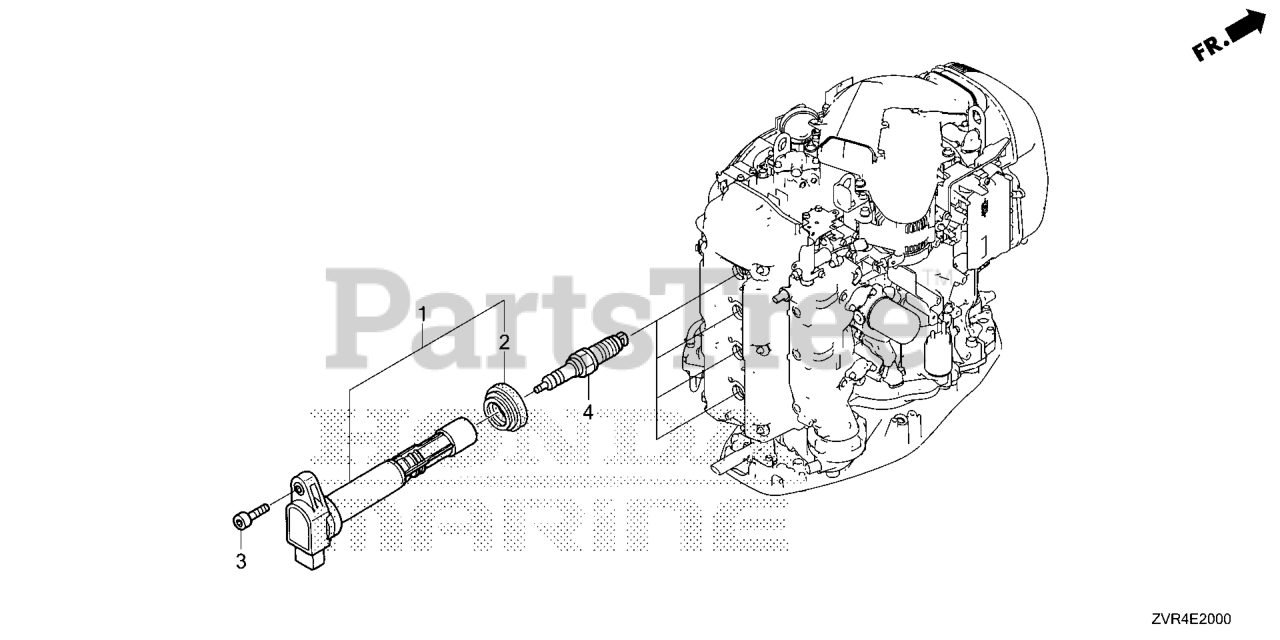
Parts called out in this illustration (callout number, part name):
1	COIL, PLUG HOLE
2	SEAL, PLUG HOLE
3	BOLT, SOCKET (6X25)
4	SPARK PLUG (KJ20DR-M11) (DENSO)
4	SPARK PLUG (SKJ20DR-M11) (DENSO)
4	SPARK PLUG (ZFR6K-11) (NGK)
4	SPARK PLUG (IZFR6K-11) (NGK)
